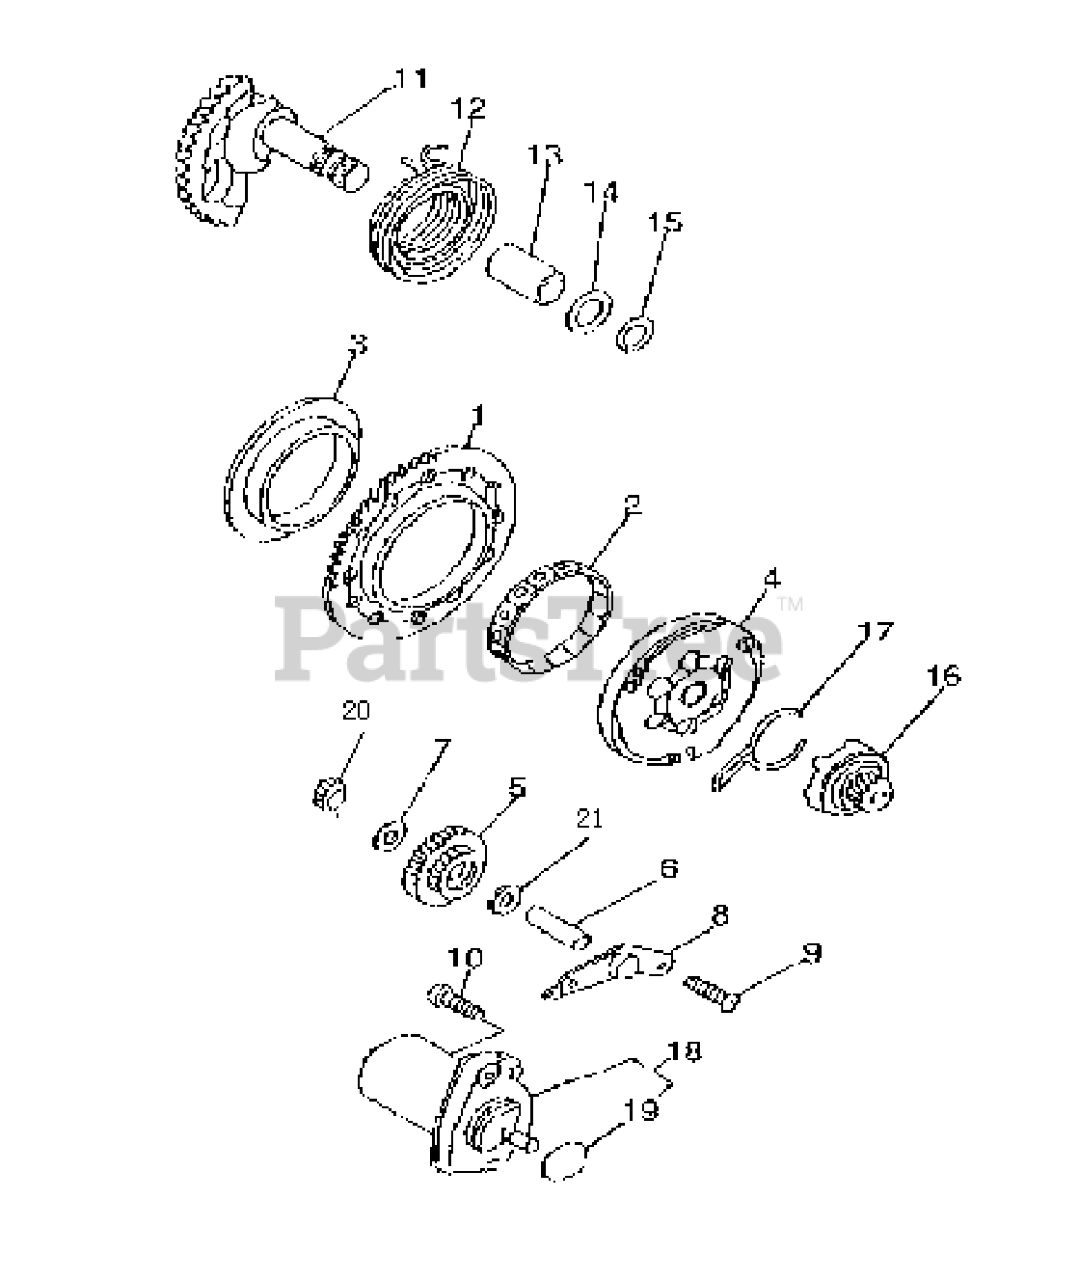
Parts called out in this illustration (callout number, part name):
1	START GEAR ASSY
2	NEEDLE BEARING
3	THRUST WASHER
4	START CLUTCH ASSY
5	IDLE GEAR
6	IDLE GEAR SHAFT
7	PLATE WASHER
8	IDLE GEAR HOLDER
11	SHAFT, KICK STARTER
14	WASHER, KICK STARTER
15	CIRCLIP
16	KICK PINION ASSY
18	STARTING ASSY
20	NEEDLE BAREING
21	PLATE WASHER
